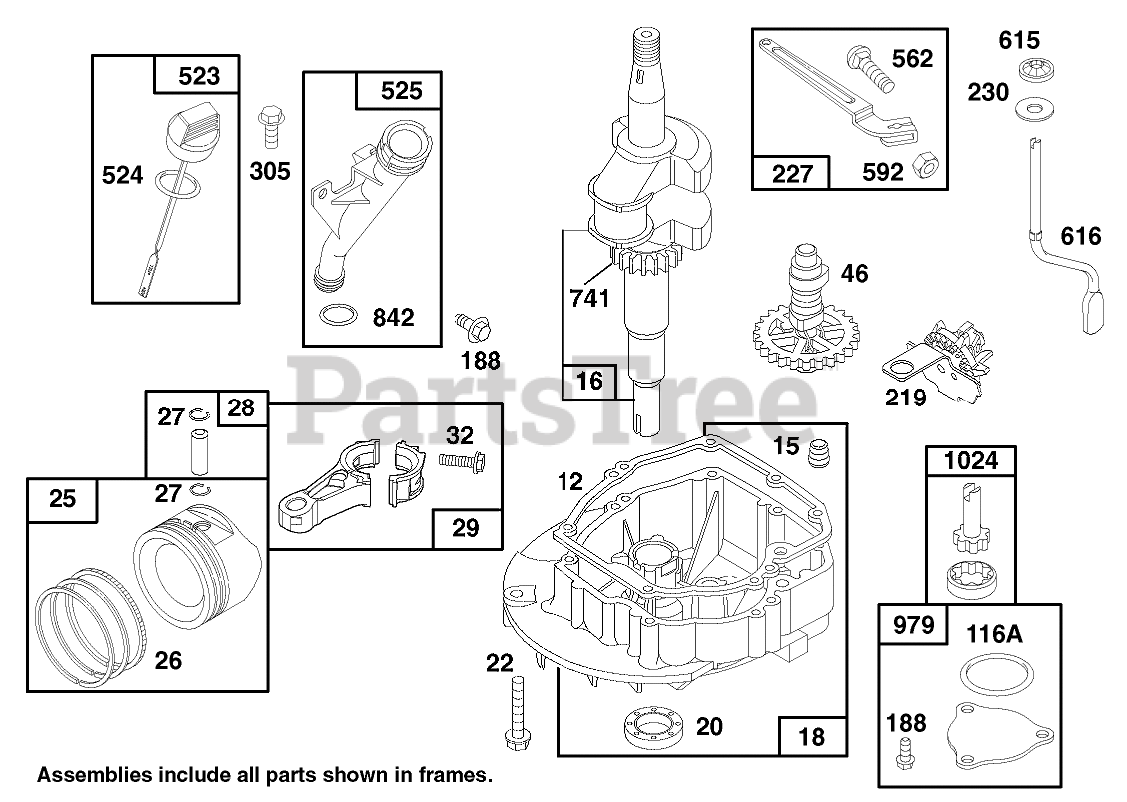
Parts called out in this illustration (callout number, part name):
12	ENGINE BASE GASKET
15	PLUG - PIPE
16	CRANKSHAFT
18	ENGINE SUMP
20	SEAL-OIL
22	SCREW - ENGINE BASE
25	STD PISTON ASSEMBLY
26	STD RING SET
27	PISTON PIN LOCK
28	PIN ASM - PISTON
29	STD PISTON ASSEMBLY
32	SCREW - CONNECTING ROD
46	CAM GEAR
116A	O RING SEAL
188	SCREW - HEX HEAD
219	GOVERNOR/OIL SLINGER
227	GOVERNOR LEVER ASSEMBLY
230	WASHER
305	SCREW - HEX HEAD
523	DIPSTICK-OIL
524	O-RING
525	OIL FILLER TUBE
562	GOVERNOR LEVER BOLT
592	HEX NUT
615	FASTENER
616	GOVERNOR CRANK
741	TIMING GEAR
842	O-RING
979	OIL PUMP COVER
1024	OIL PUMP
